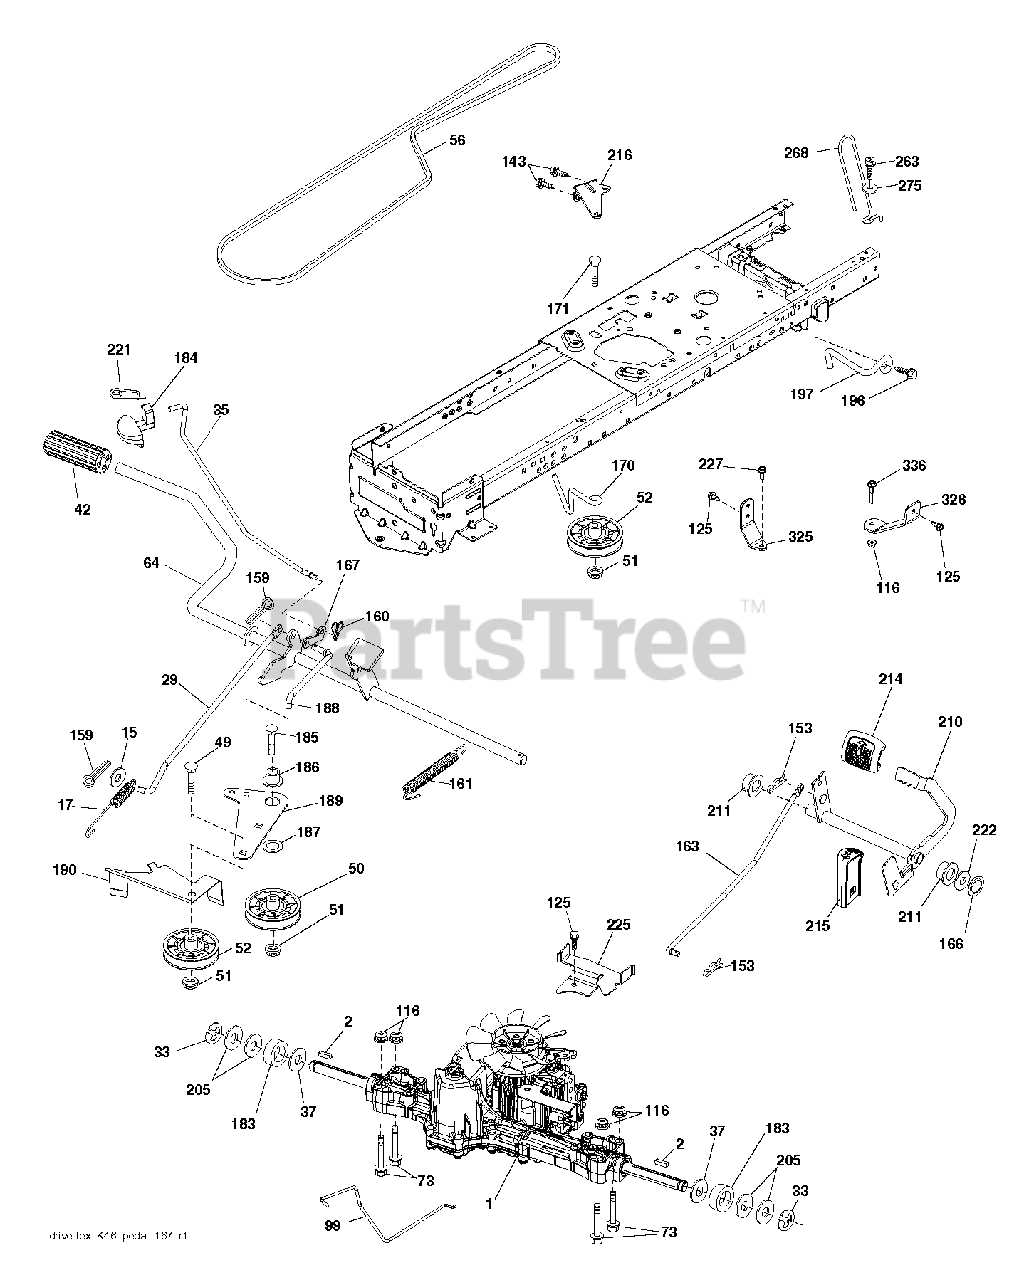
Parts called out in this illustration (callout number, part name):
2	SQUARE KEY
15	WASHER
17	SPRING.BRAKE.K46.GREEN
29	ROD.BRAKE.K46
35	ROD.CNTRL.PARK.PREDATOR.LT.TEX
37	WASHER.HARDENED
42	PEDAL COVER T
50	IDLER.FLAT.910.OFFSET
51	NUT LOCK FLG 3/8-16 UNC
52	IDLER.V-GROOVE.910.OFFSET
56	V-BELT.MOWER.92.40.42/K46
64	SHAFT.ASM.PEDAL.BRK.CNTR
99	ROD.SPRING.BYPASS.K46.LT.Z
116	NUT LOCK HEX FLANGE 5/16-18
125	SCREW
143	SCREW LT
153	RETAINER M
159	COTTER PIN
160	RETAINER CLIP
161	SPRING, RETURN LT
163	ROD.CONTROL.K57R.K46
166	NUT.PUSH.625
167	LATCH.BRAKE.SPRING
170	KEEPER.V-IDLER.CENTER.
183	SPACER AXLE
184	HANDLE.PARKING.BRK.PRED.LT.RED
186	SPACER.RETAINER
187	WASHER 12/32X2X10GA
188	RP LINK.CLUTCH.GROUND.DRIVE
189	BELLCRANK.GROUND.DRIVE.TEX.
190	KEEPER.BELLCRANK.DRIVE
196	SCREW 3/8-16X1
197	CLUTCH.ANTIROTATION.WIREFORM.
210	ROCKER.ASM.PEDAL.CONTR
211	BEARING.NYLON
214	PEDAL.FORWARD.PAD.TEX
215	PEDAL.COVER.REVERSE.CRD.X428BK
216	BRACKET.PULLEY.IDLER.W/TEX
221	RETAINER.SPRING.CLIP.H
222	WASHER 21/32 X 1-1/4 X 10 GA.
225	KEEPER.BELT.TRANSAXLE.K46
227	SCREW
263	SCREW, 3/8-16X3/4
268	GUARD MUFFLER
275	WASHER
325	BRACKET.TRQ.STP.46.20".TIRE.LH
326	BRCKT.PNT.TRQ.STP.46.20TIRE.RH
336	BOLT.5/16-18X1-3/4.FLANGED.HEX
